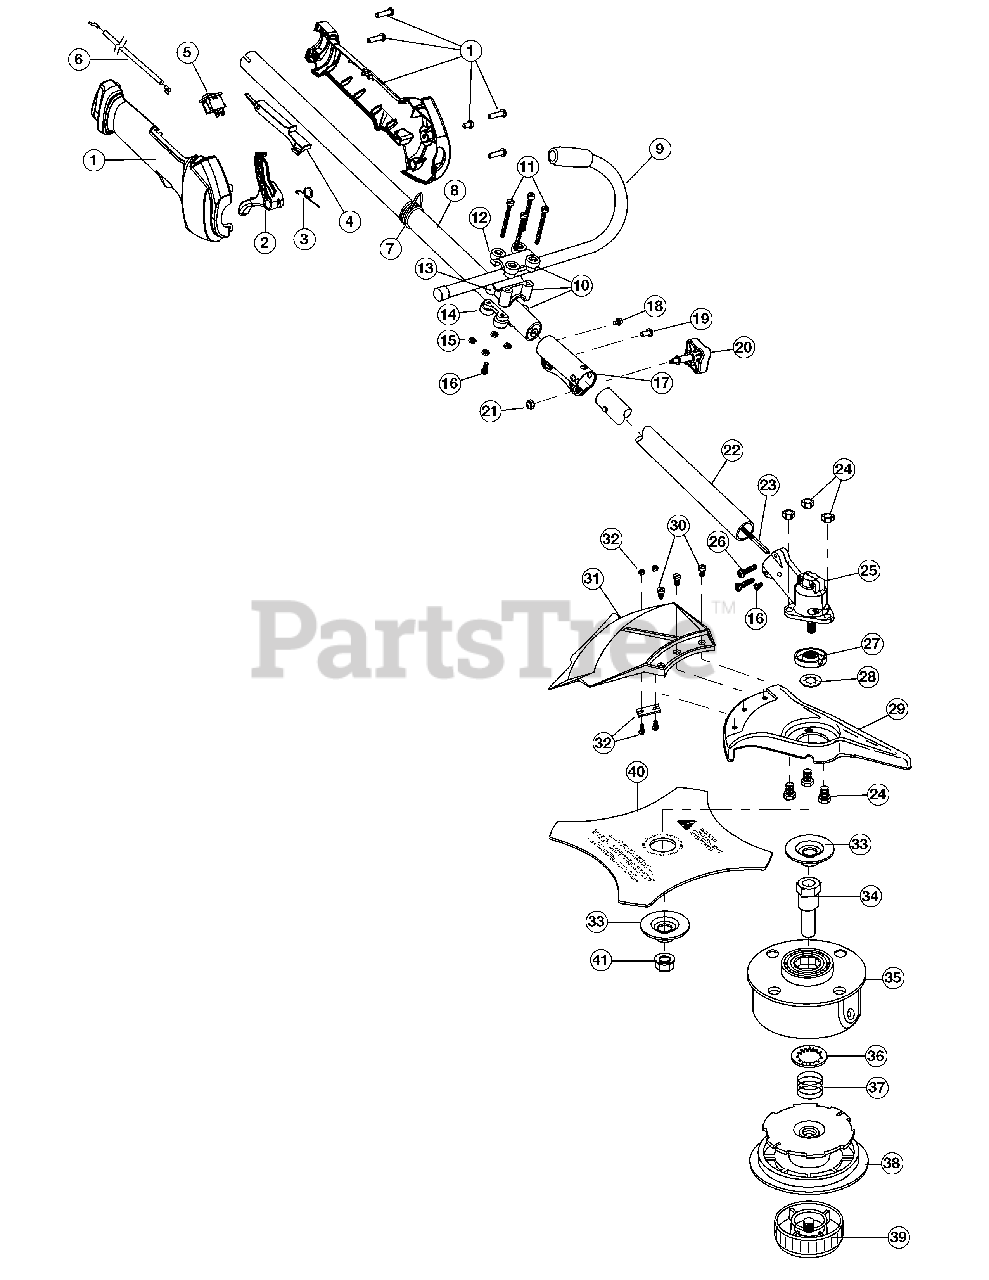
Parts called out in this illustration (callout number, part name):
1	Throttle Housing Assembly (Incl. 2 - 5)
2	Throttle Trigger
3	Throttle Trigger Spring
4	Throttle Trigger Lock-Out
5	Switch Assembly
6	Throttle Cable Assembly
7	Harness Clip
8	Upper Drive Shaft Housing Assembly
9	J-Handle Assembly
10	Handle Bracket Assembly (Incl. 11 - 16)
12	Upper Handle Clamp
13	Middle Handle Clamp
14	Lower Handle Clamp
16	Anti-Rotation Screw
17	Split Boom Coupler (Incl. 18 - 21)
20	Adjustment Knob
21	Knob Retaining Nut
22	Lower Drive Shaft Housing Assembly
23	Lower Flexible Drive Shaft
24	Shield Mount Screw Assembly
25	Gearbox Assembly (Incl. 16 & 26 - 28)
26	Gearbox Mounting Hardware
27	Blade Driver
29	Blade Shield/Shield Mount
30	Shield Mounting Screw
31	Shield Assembly (Incl. 32)
32	Blade Assembly
33	Retaining Washer
34	Spool Shaft
35	Outer Spool Assembly
36	Retainer
39	Bump Head Knob Assembly
40	4-Tooth Blade
